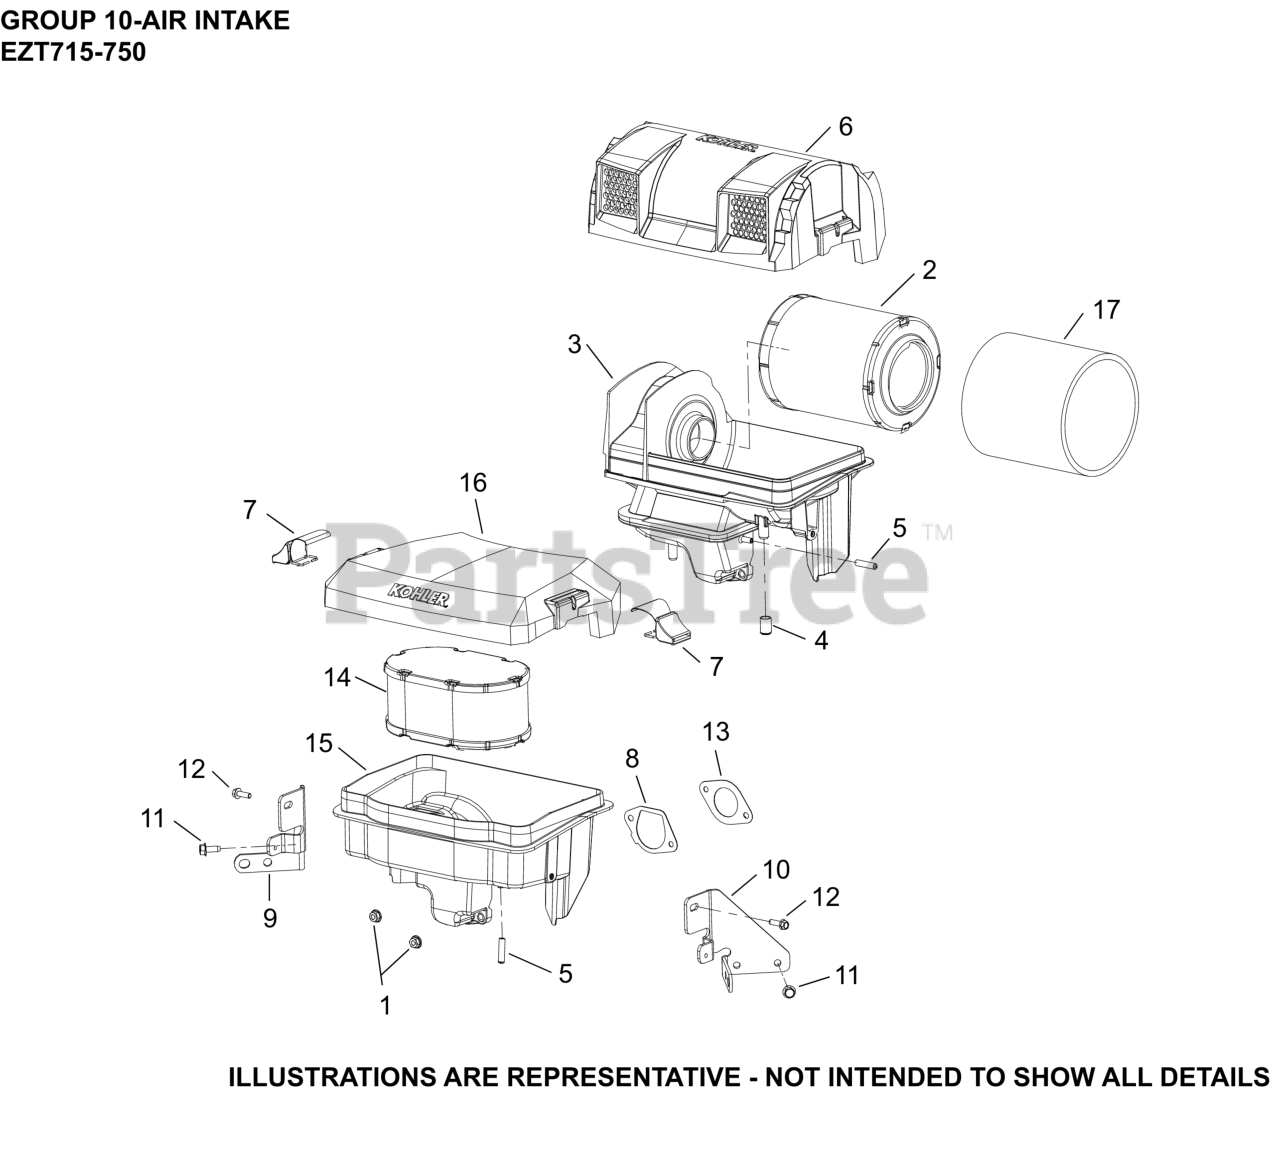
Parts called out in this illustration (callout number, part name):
1	NUT, FLG M6X1.0
2	ELEMENT, AIR FILTER
3	BASE ASSEMBLY, AIR CLEANER (HDAC)
4	CAP, MASKING
5	CAP, MASKING
6	COVER, AIR CLEANER (HDAC)
7	LATCH ASSY, AIR CLEANER COVER
8	GASKET, AIR CLEANER BASE
9	BRACKET, AIR CLEANER BASE (#1 SIDE)
10	BRACKET, AIR CLEANER BASE (#2 SIDE)
11	SCREW, THREAD FORMING
12	SCREW, HI-LOW
13	GASKET, THROTTLE BODY
17	ELEMENT, PRE-CLEANER
